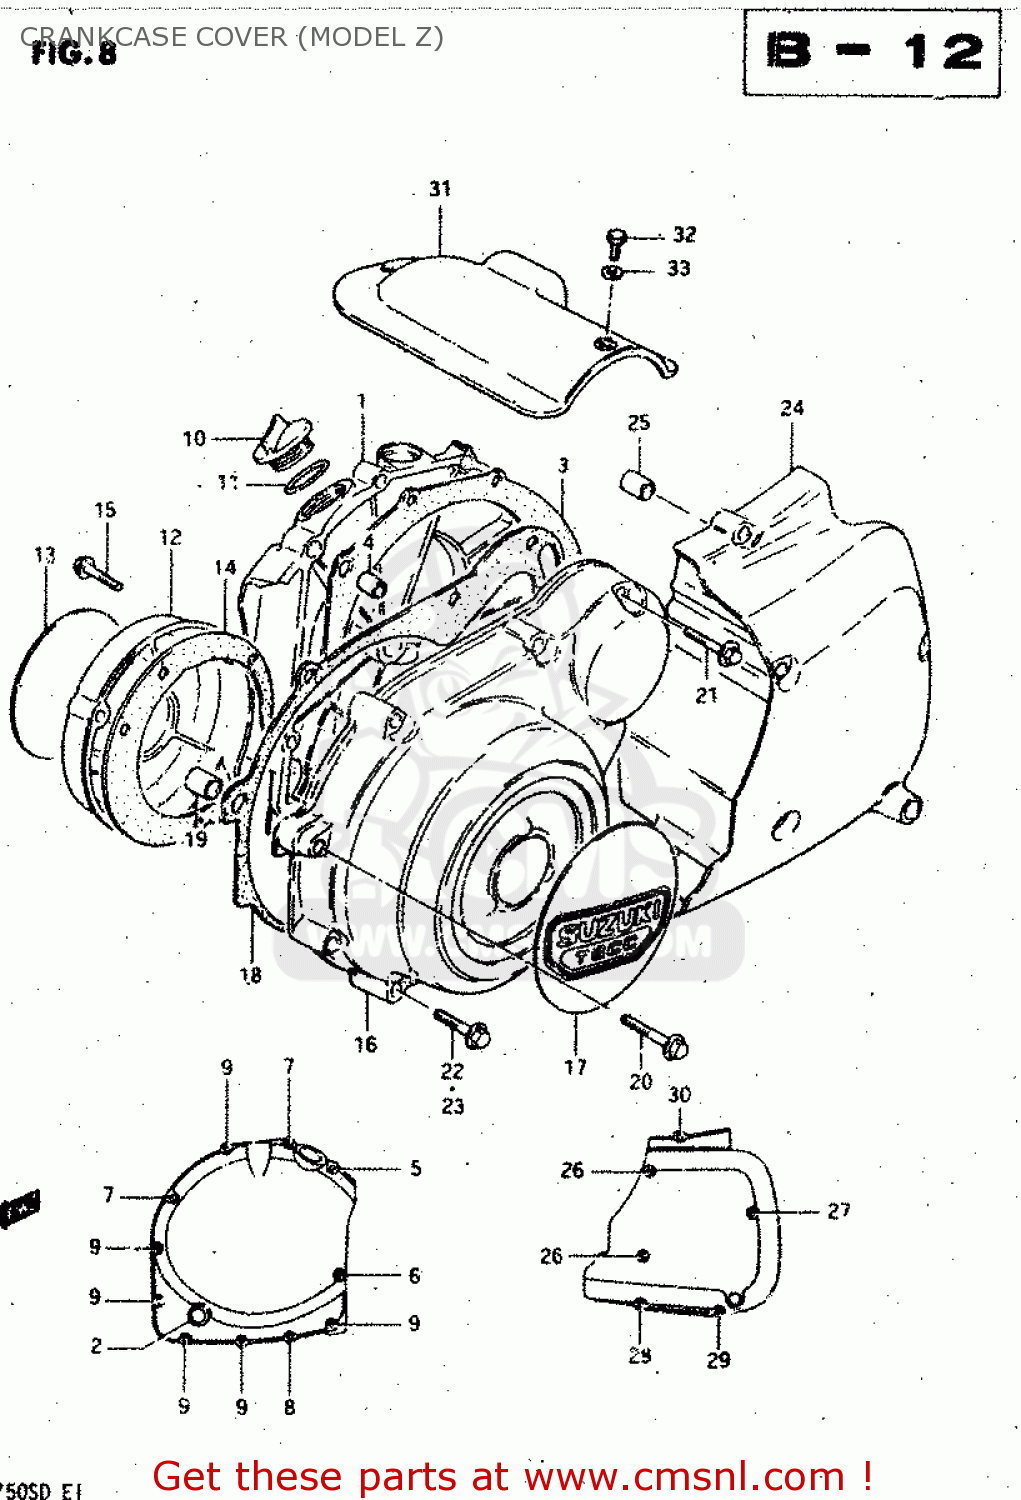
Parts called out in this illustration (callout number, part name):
1	COVER,CLUTCH
2	LENS,OIL LEVEL CHECK
3	GASKET,CLUTCH COVER (MCA)
4	PIN
5	BOLT (6X40)
6	BOLT (6X35)
7	BOLT (6X30)
8	BOLT
9	BOLT (6X20)
10	CAP
11	O RING(D:2.2,ID:32)
12	COVER,CONTACT BREAKER
13	EMBLEM
14	GASKET,CONTACT BREAKER COVER (NAS)
15	BOLT (5X30)
16	COVER,MAGNETO
17	EMBLEM
18	GASKET,MAGNETO COVER (MCA)
19	PIN
20	BOLT
21	BOLT (6X40)
22	BOLT (6X35)
23	BOLT (6X30)
24	COVER,ENGINE SPROCKET
25	PIN
26	BOLT 6X95
27	BOLT (6X85)
28	BOLT (6X70)
29	BOLT (6X55)
30	BOLT (6X30)
31	COVER,STARTER MOTOR
32	BOLT 5X10
33	WASHER
